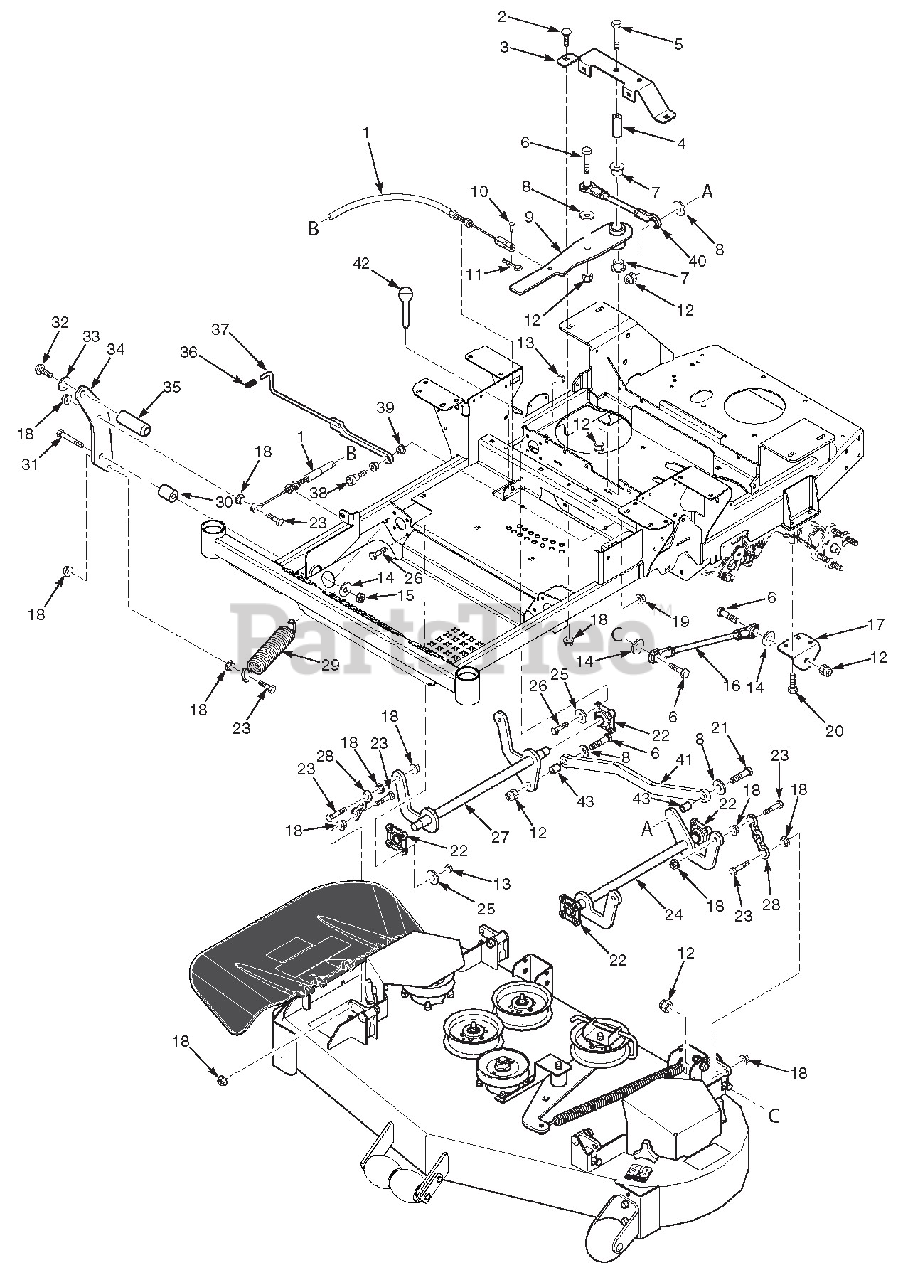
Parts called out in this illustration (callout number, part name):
1	Cable, Deck Lift
2	Bolt, Carriage 3/8-16 x 3/4"
3	Support, Idler Arm
4	Spacer, Deck Lift Pivot
5	Bolt, Hex Head 1/2-13 x 3-3/4"
6	Bolt, Hex Head 1/2-13 x 2"
7	Bearing
8	Flatwasher, 1/2-.531 x 1.06 x .095
9	Deck Lift Bellcrank Assembly
10	Clevis Pin, 5/16 x 3/4"
11	Hair Pin, .094 x 1.62"
12	Nut, Elastic Stop 1/2-13
13	Nut, Elastic Stop 5/16-18
14	Flatwasher, 1/2-.562 x 1.375 x .109
15	Nut, Center Lock 1/2-13
16	Linkage, Push Arm
17	Bracket, Push Arm Link
18	Nut, Serrated Flange 3/8-16
19	Nut, Elastic Stop 3/8-16
20	Bolt, Hex Head 5/16-18 x 3"
21	Bolt, Hex Head 1/2-13 x 2-3/4"
22	Bearing, Deck Lift
23	Bolt, Hex Head 3/8-16 x 1-1/2"
24	Weldment, Deck Lift LH
25	Flatwasher, 1/4-.312 x .750 x .065
26	Bolt, Hex Head 5/16-18 x 1"
27	Weldment, Deck Lift RH
28	Chain, Deck lift
29	Spring, Deck Lift
30	Sleeve, Deck Lift Pivot
31	Bolt, Hex Head 1/2-13 x 3"
32	Bolt, Head Socket 5/8-11 x 1-1/2"
33	Lockwasher, 5/8 Spring
34	Pedal, Foot Bracket
35	Foot Pedal
36	Grip, Deck Latch
37	Weldment, Deck Latch
38	Bolt, Shoulder 1/2 x 1/2
39	Bearing
40	Linkage Assembly, Deck Lift
41	Link, Deck Lift
42	Pin, Height Adjuster
43	Sleeve
